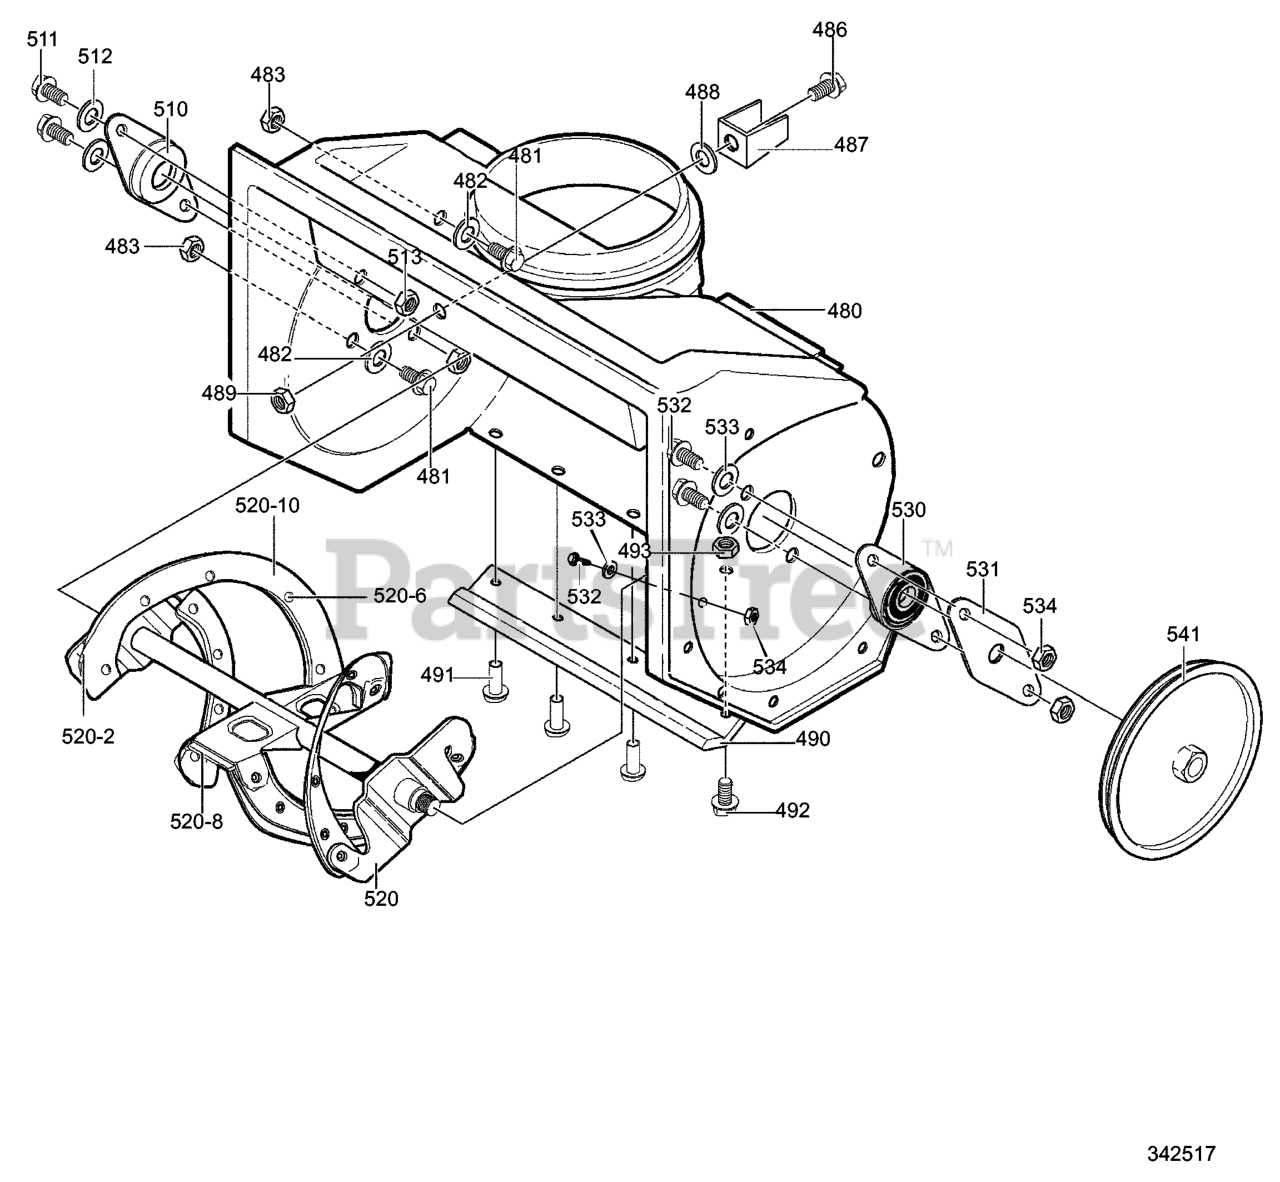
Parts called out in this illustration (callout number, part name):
480	HOUSING, ASSY
481	SCREW, 1/4-20X.75
482	WASHER, FLAT .281X.63X.065
483	NUT, HEX 1/4-20 YZ
486	SCREW, 1/4-20X.63
487	BRACKET, STOP
488	WASHER, FLAT .333 X .87 X .119
489	NUT, 1/4-20 HEX NYLOCK
490	BLADE, SCRAPER
491	RIVET, OVSET
492	SCREW, 1/4-20X.75
493	NUT, 1/4-20 YZ
510	BEARING, FLANGE
511	SCREW, 1/4-20X1.00
512	WASHER, FLAT .281X.63X.065
513	NUT, 1/4-20 YZ
520	AUGER, ASSY
520-2	BLADE, AUGER
520-6	RIVET
520-8	BLADE, CENTER
520-10	AUGER & BLADE SUPPORT
530	BEARING & PLATE ASSY
531	PLATE, RETAINER
532	SCREW, 1/4-20X.63
533	WASHER, FLAT .281X.63X.065
534	NUT, 1/4-20
